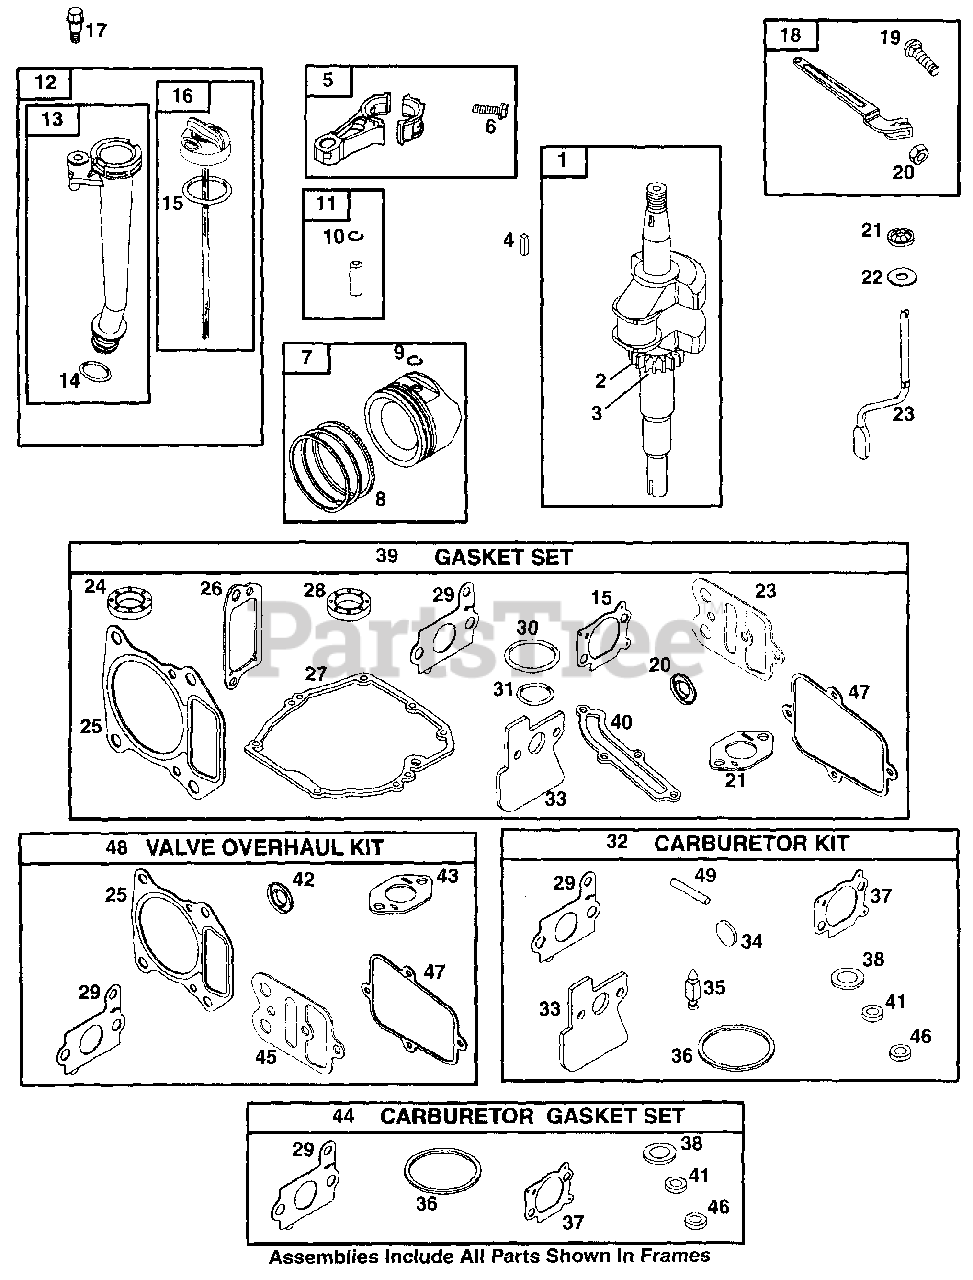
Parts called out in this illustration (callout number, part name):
1	Crankshaft
2	Timing Gear
3	Timing Key
4	Flywheel Key
5	Connecting Rod
6	Connecting Rod Screw
7	Piston Assembly (Standard)
8	Ring Set (Standard)
9	Piston Pin Lock
10	Piston Pin Lock
11	Piston Pin (Standard)
12	Dipstick/Tube Assembly
13	Oil Fill Tube
14	Seal-O-Ring
15	Seal-O-Ring
17	Shoulder Screw
18	Governor Lever
19	Governor Lever Bolt
21	Governor Shaft Retainer
22	Flat Washer
23	Governor Crank
24	Oil Seal
25	Cylinder Head Gasket
26	Breather Gasket
27	Crankcase Gasket
28	Oil Seal
29	Intake Gasket
30	Seal-O-Ring
31	Seal-O-Ring
32	Carburetor Kit
33	Carburetor Spacer
34	Welch Plug
35	Needle Valve
36	Float Bowl Gasket
37	Air Cleaner Gasket
38	Seal Washer
39	Gasket Set
40	Breather Passage Gasket
41	Choke Shaft Seal
42	Valve Seal
43	Exhaust Gasket
44	Carb. Gasket Set
45	Throttle Shaft Gasket Seal
46	Throttle Shaft Seal
47	Rocker Cover Gasket
48	Valve Overhaul Kit
49	Float Hinge Pin
